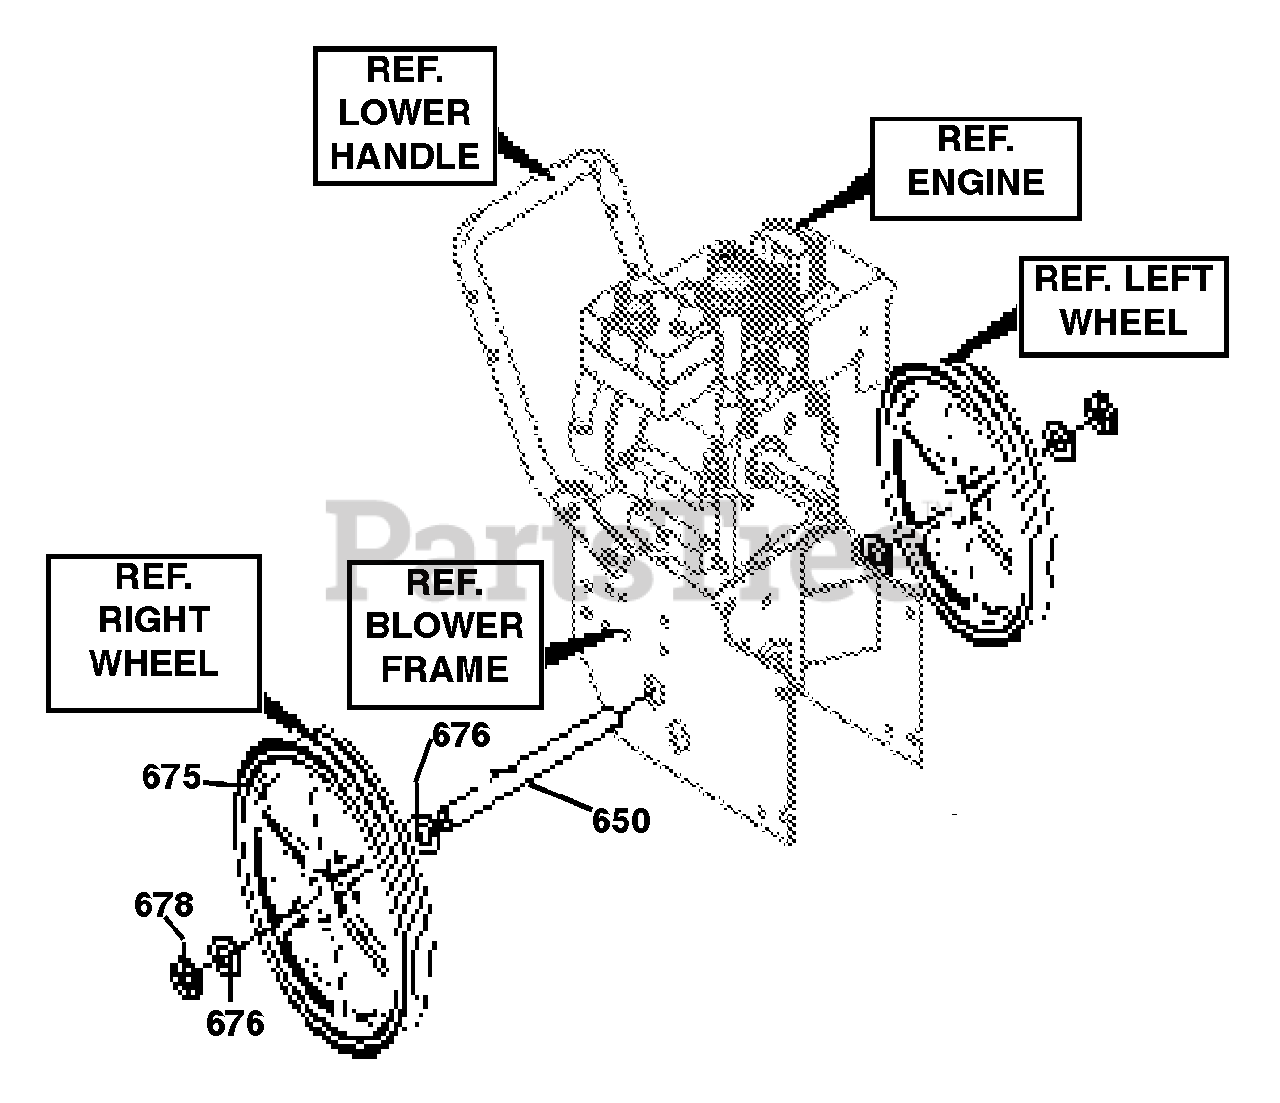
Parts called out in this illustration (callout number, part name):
650	Axle, .50 x 20"
675	Tire & Rim
676	Flatwasher, .53 x 1.00 x .063
678	Ring Retaining E
